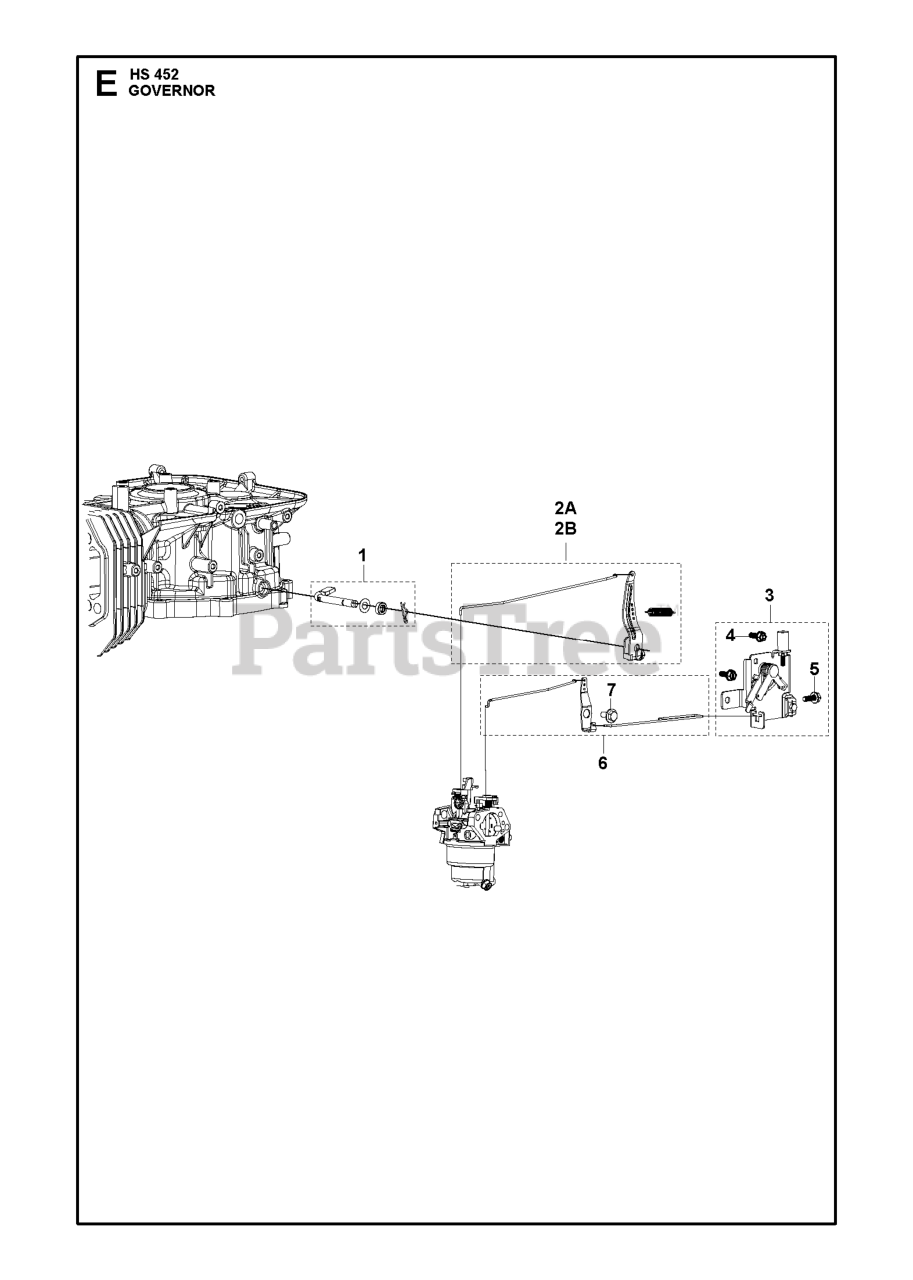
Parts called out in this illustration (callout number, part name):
1	SERVICE KIT KIT.SPEED REGULATI
2A	THROTTLE ASSY THROTTLE ASSY
3	THROTTLE HANDLE THROTTLE HANDL
4	Husqvarna TBD
6	CHOKE ROD CHOKE ROD
7	BOLT T370: M6 L=15
